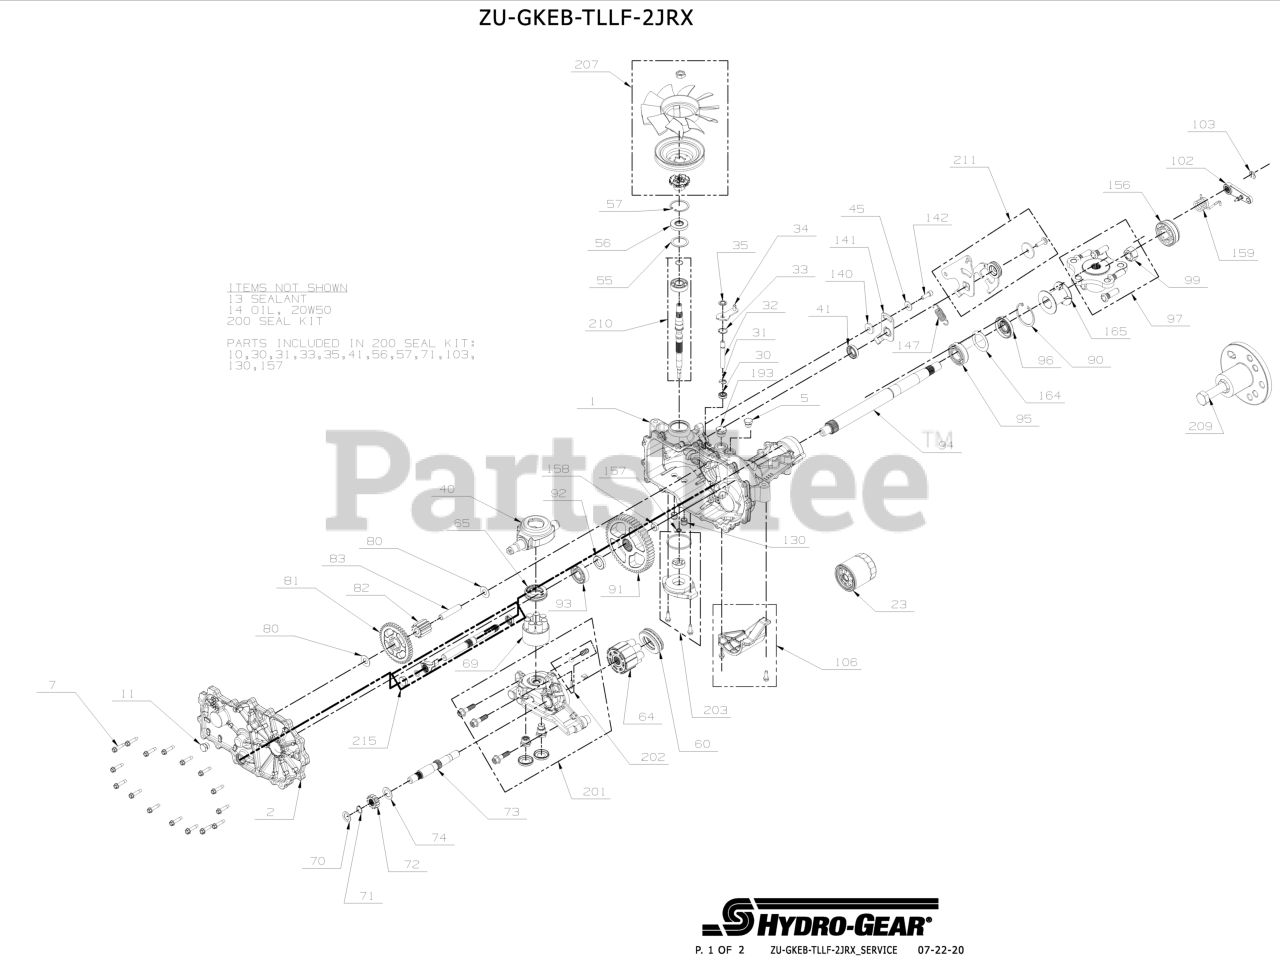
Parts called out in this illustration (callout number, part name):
1	KIT, MAIN HOUSING RH, CHARGE, CONTROL
2	KIT, COVER, SIDE RH
5	PLUG EXT HEX VENT 9/16 18
7	SCREW,HEX WASHER 1/4-20X1.125
11	PLUG EXT HEX VENT 9/16 18
13	SEALANT TUBE 10.1OZ.
14	FLUID, HYDRO 15W50 QT
14	FLUID, HYDRO 20W50 QT
23	FILTER, HYDRO-GEAR 2800 TRANS
30	Seal, lip .375 x 375 x 325
31	RING. RETAINING
32	ROD, BYPASS
33	RING, RET .750
34	ARM, BYPASS
35	RING, RTNG .
40	TRUNNION, SWASHPLATE
41	SEAL, LIP 18X32X7
55	WASHER 1.23X1.56X.04
56	SEAL, LIP 17X40X7
57	RING, RET 1.56 INT
60	HG THRUST BEARING (51462)
64	HG 16CC CYLINDER BLOCK (71579)
65	HG THRUST BLOCK (53502)
69	HG SEVEN PISTON BLOCK (71971)
70	WASHER .63X1.0X.05
71	RING, RET 62 EXT
72	GEAR, 13T, STEEL
73	SHAFT, MOTOR
74	WASHER .71 X 1.16 X .04
80	WASHER .5X1.0X.032
82	GEAR 11 TOOTH STEEL
83	JACK SHAFT (PIN)
90	RING, RETAINING
91	GEAR, 54T
92	SPACER
93	KIT, BEARING
94	SHAFT, AXLE
95	BEARING, BALL 25.4 X 52 X 15
96	SEAL, LIP
97	HUB, HYDROGEAR P/N 71691
99	NUT, HEX, LOCK 3/4-16
102	BRAKE ARM HG 71957
103	CLIP,BRAKE ARM HYDROGEAR 52027
106	KIT FILTER GUARD
130	TUBE CHARGE TRIPLE ORING
141	ARM, NEUTRAL RIGHT
142	SHCS 5/16-24X1 PATCH
147	RTN SPRING HG 51605
156	CAP, AXLE
157	KIT GEROTOR SEAL
158	MAGNET, RING
159	SPRING, TORSION CCW
164	WASHER, 1.355 x 2.035 x .021 FLAT
165	TUBE, AXLE 2.03
200	HG SEAL KIT (71976)
201	KIT CNTR SEC RH CHARGE
202	KIT CHARGE RELIEF
203	KIT, CHARGE PUMP
207	KIT, FAN/PULLEY
209	HUB PULLER 5 BLT
210	INPUT SHAFT HG 71978
211	RTN KIT HYDROGEAR P/N 71597
215	KIT, OUTBOARD, RH ROT A / LH ROT B
